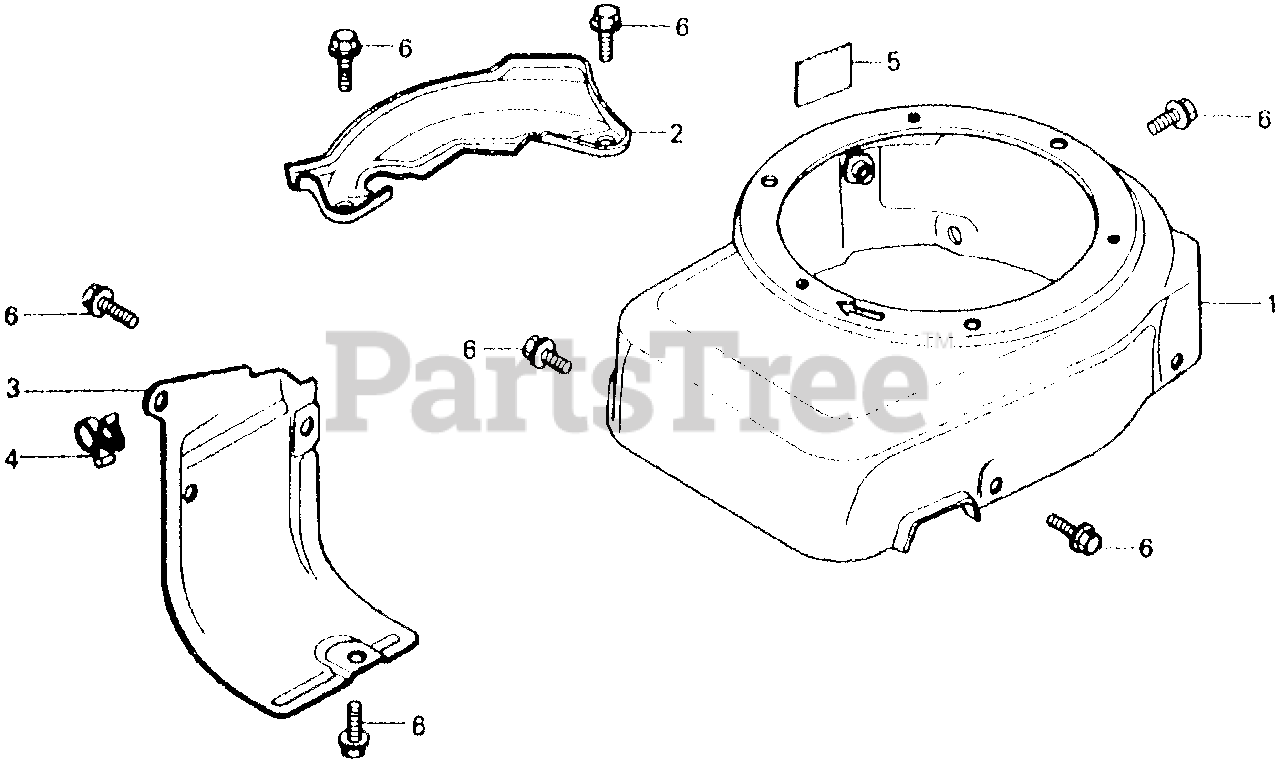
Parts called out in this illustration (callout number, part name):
1	COVER, FAN *NH67* (SPARKLE WHITE)
2	PLATE, SIDE
3	SHROUD
4	CLIP, IGNITION WIRE (8MM)
5	MARK, OIL CAUTION
6	BOLT, FLANGE (6X12) (CT200)
